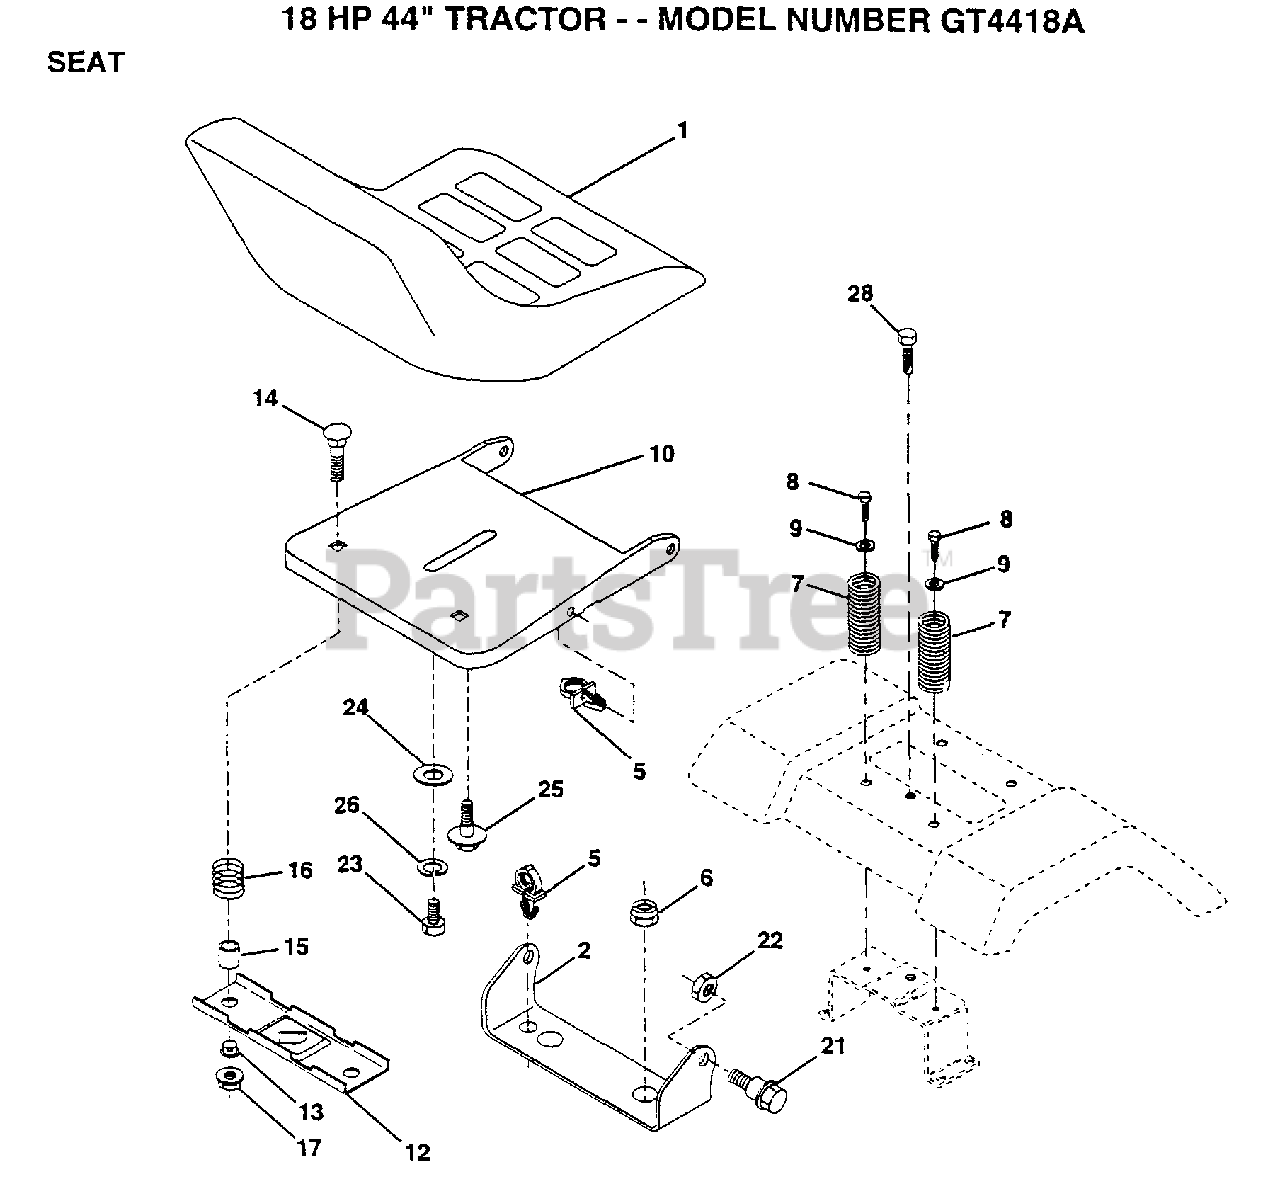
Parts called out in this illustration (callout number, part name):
2	BRACKET PVT SEAT
5	CLIP PUSH - IN
7	SPRING COMPRESSIO
8	SCREW LT
9	WASHER
12	BRKT SWITCH
13	BUSHING
15	SPACER SPLIT
16	SPRING COMPRESSED
21	BOLT.SHLD.5/16-18
23	BOLT
24	WASHER
25	"BOLT,SHOULDER"
26	LOCKWASHER
28	SCREW LT
